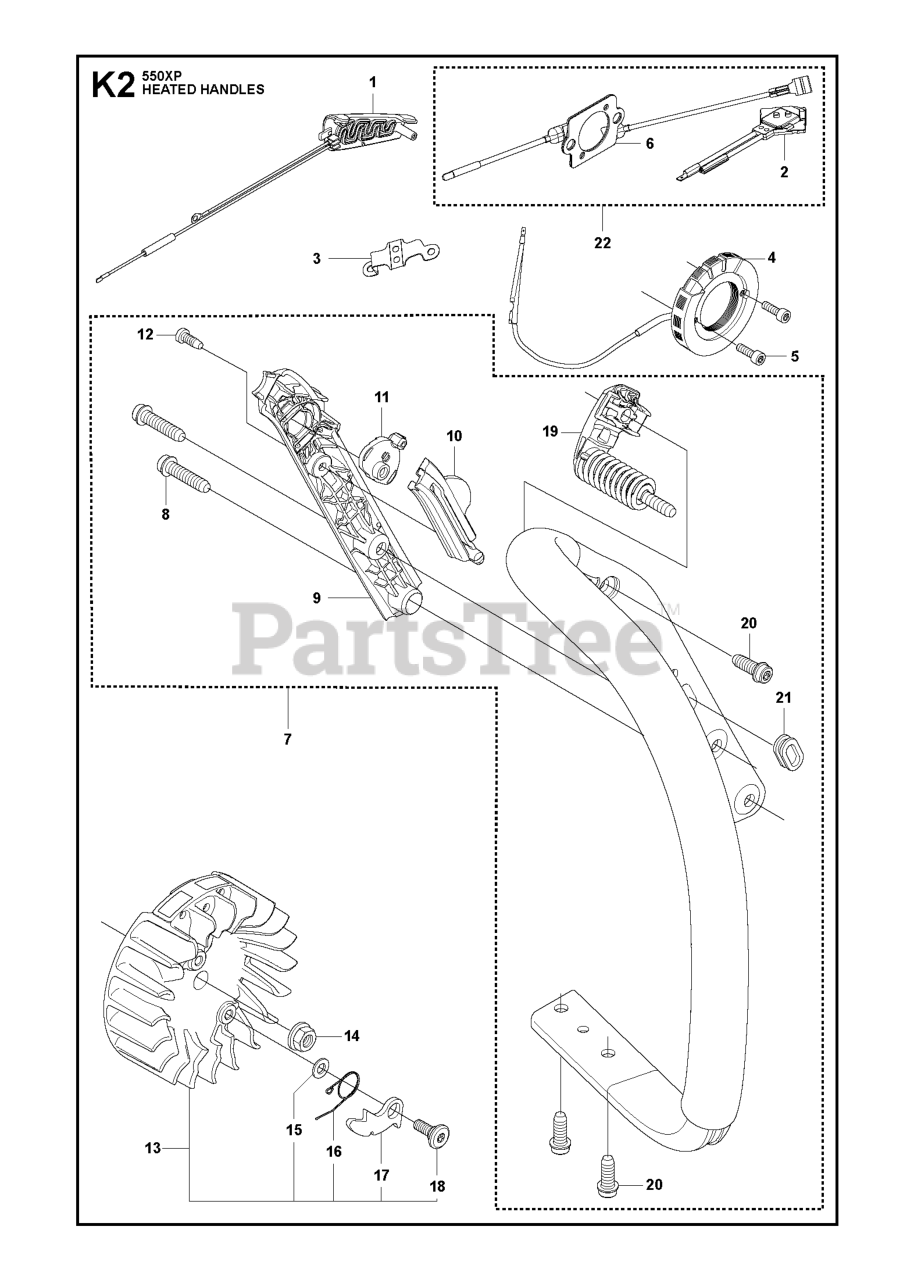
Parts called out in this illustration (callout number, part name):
1	HANDLE INSERT
2	THERMOSTAT ASSY
4	GENERATOR STATOR
5	SCREW ITXSCM M4X15 T27 12.9 T
6	FOIL ELEMENT
7	FRONT HANDLE
10	CONTACT PLATE
12	SCREW CITXPANT
13	FLYWHEEL ASSY
14	NUT W/ WASHER
18	SCREW
19	ANTIVIBRATION ELEMENT
20	SCREW ITXSCFT PL6X16 T27 10.9
22	THERMOSTAT ASSY
